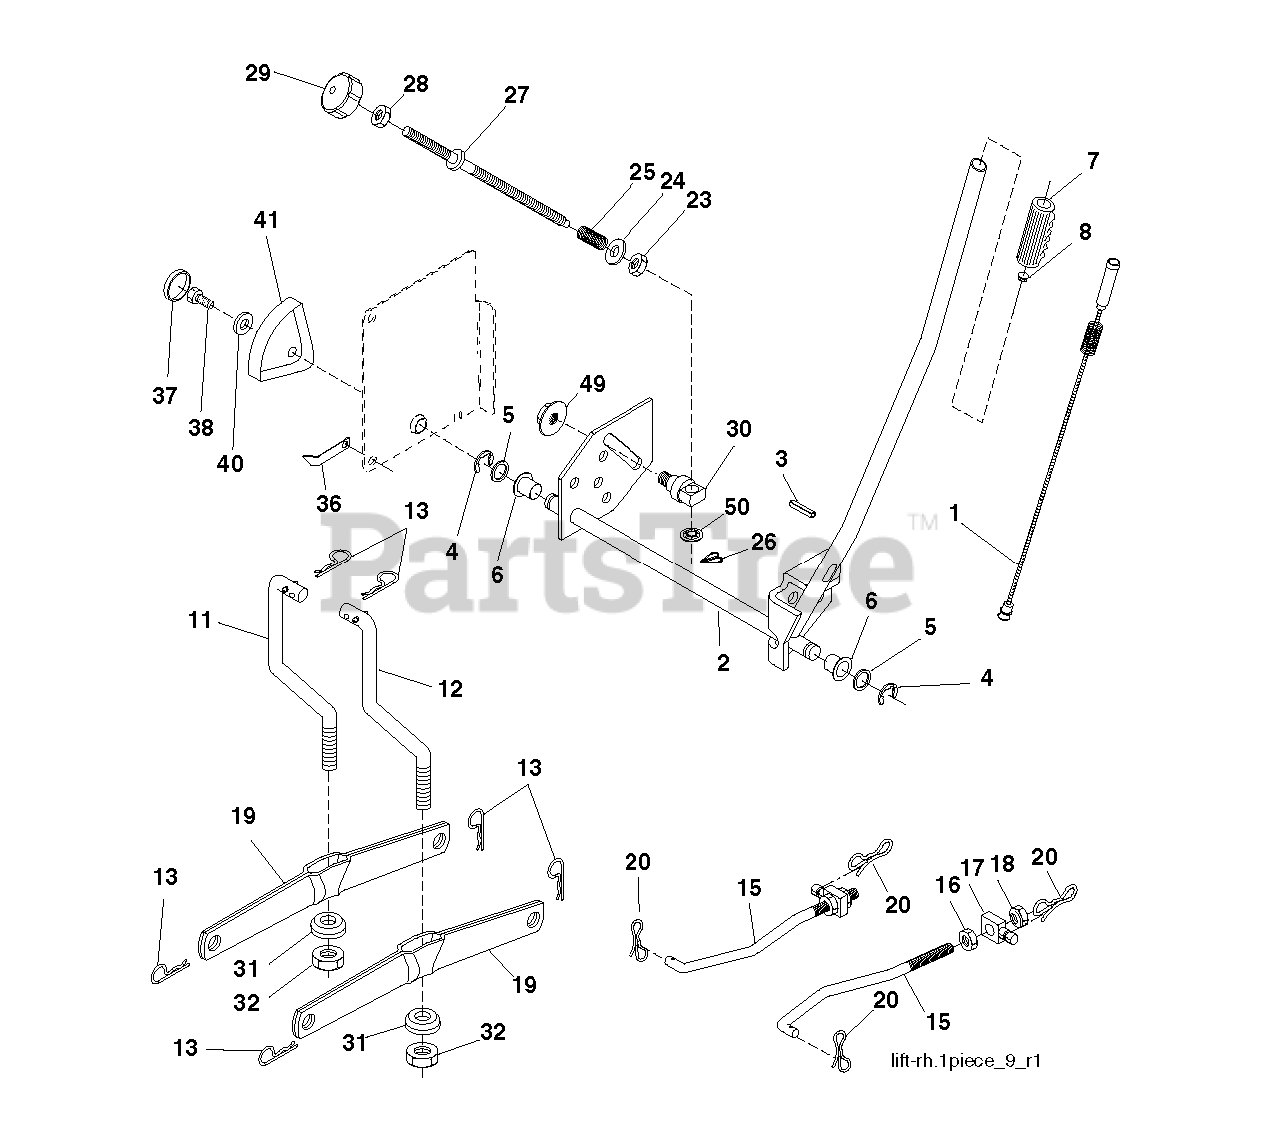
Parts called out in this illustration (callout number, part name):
1	PLUNGER.ASM.LIFT.LEVER.BLK.
2	SHAFT.ASM.LIFT.YT
3	PIN.GROOVE.5/16
4	RETAINING RING LT
6	BEARING.NYLON
7	GRIP HANDLE
8	REPL BY 532 12 59-25
11	LINK
12	LINK
13	RETAINER-SPRNG RB
15	LINK.SUSPENSION.FRONT
16	NUT.HEX.JAM.1/2-13
18	NUT.LK.W/WSH.1/2.
19	ARM.REAR.SUSPENSION
20	PIN.COTTER.7/16.BOW TI.
26	RETAINER CLIP
27	ROD ADJ LIFT
28	NUT
29	KNOB INF 3/8-16
31	BEARING.PIVOT.LIFT
32	NUT CROWNLOCK 3/8-24
36	POINTER, HEIGHT INDICATOR(2 2)
38	SCREW 5/16-18X1
41	HEIGHT INDICATOR
49	NUT
50	NUT PUSH M
